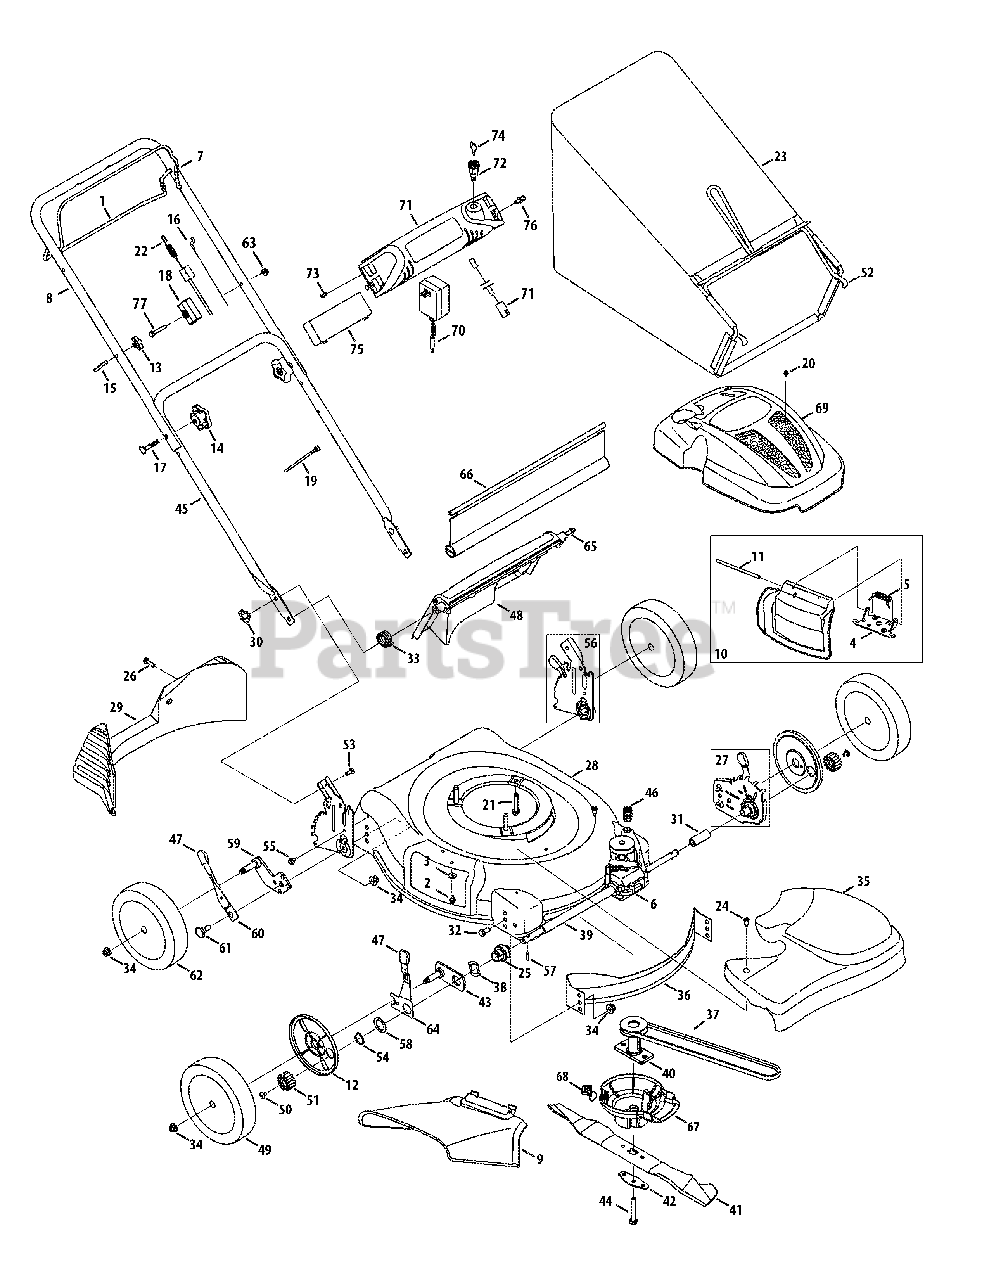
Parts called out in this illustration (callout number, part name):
1	Drive Control
2	TT Screw 1/4-20 x 0.5
3	Bell Washer.265 x 0.75
4	Deflector Chute Adapter
5	Torsion Spring
6	Transmission Assembly
7	Blade Control
8	Upper Handle
9	Chute Deflector
10	Mulch Plug Complete
11	Hinge Pin
12	Wheel Dust Cap
13	Handle Knob
14	Star Knob
15	Eye Bolt
16	Control Cable
17	Carriage Bolt 5/16-18 x 2.0
18	Control Cable Mount
19	Cable Tie
19	Guide. Cable
20	Screw, HL, #12-16 x 1.00
21	Self-Tapping Sems Screw
22	Drive Cable
23	Grass Bag
24	Shoulder Screw # 12 -24
25	Front Bearing Assembly
26	Screw, 1/4-15 x 1.000
27	Height Adjustment Ass’y - RH
27	Height Adjustment Ass’y - LH
29	Rear Baffle
30	Wing Nut
31	Slev. Spacer 1.4" Lg.
32	Hex Screw, 3/8-16 x.75
33	Torsion Spring - RH
34	Flange Lock Nut, 3/8-16
35	Transmission Cover
36	Front Baffle
37	V-Belt
38	Wave Washer
39	Sleeve Spacer 8.985" Lg.
40	One Piece Blade Adapter
41	21" Mulching Blade
42	Blade Bell Support
43	Pivot Plate Assembly
44	Hex Screw 3/8-24 x 2.50
45	Lower Handle
46	Belt Tension Spring
47	Adjustment Knob
48	Rear Discharge Door
49	Front Wheel
50	Screw, 1/4-20 x .390
51	Gear 14T RH FWD
51	Gear 14T LH FWD
52	Grass Bag Frame
53	Carriage Bolt 1/4-20
54	Snap Ring
55	TT Scr. w/Washer 1/4-20 x.625
56	Handle Bracket Assembly - RH
56	Handle Bracket Assembly - LH
57	Dowel Pin
58	Washer
59	Pivot Arm Assembly - RH
59	Pivot Arm Assembly - LH
60	Rear Spring Lever
61	Shoulder Scr.500 Dia. x.434
62	Rear Wheel
63	Nut, Flglk, 1/4-20
64	Front Lever - RH
64	Front Lever - LH
65	Pivot Rod
66	Rear Trailing Shield
67	Engine Baffle
68	Engine Baffle Bracket
69	Engine Shroud
70	Battery Charger
70	Battery Charger (w/LED Light)
71	Electric Start Harness Assembly
72	Key Switch
73	Screw, #10-16 x .750
75	Battery
76	Rivet
77	Screw, 1/4-20 x 1.50
